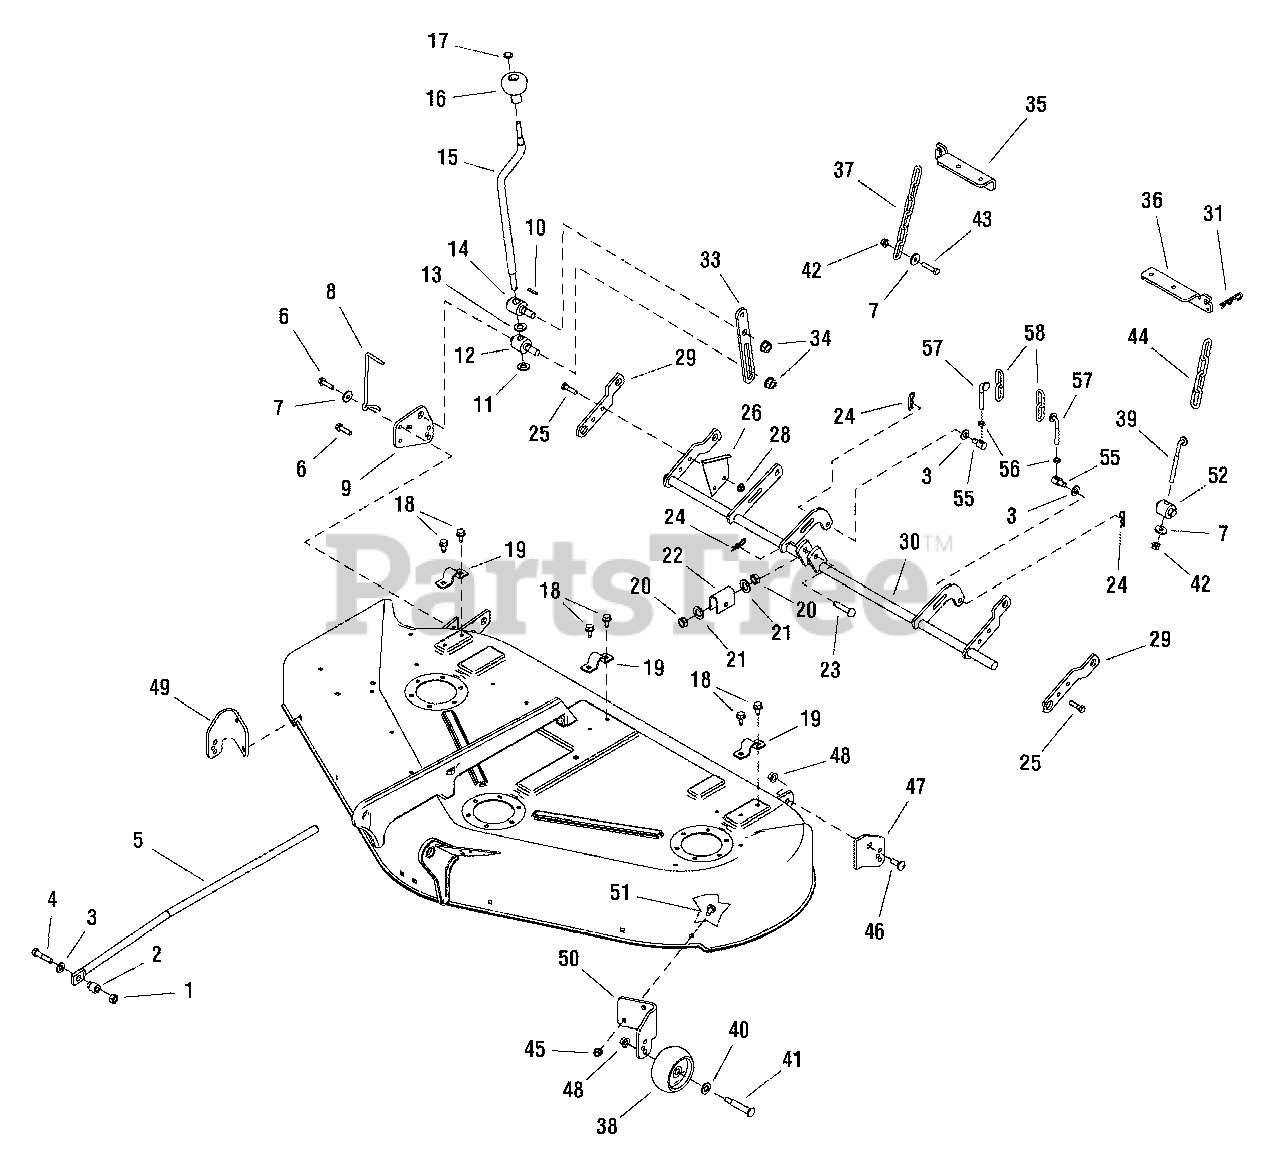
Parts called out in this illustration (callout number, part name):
1	NUT, Hex Flange, 3/8-16
2	SPACER, 3/8 x 3/4 x 15/16
3	WASHER, 3/4
4	CAPSCREW, Hex Head, 3/8-16 x 1-3/4
5	ROD, Adjusting
6	SCREW, Hex Washer Head Taptite 5/16-18 x 1-1/4
7	WASHER, 5/16
8	INDICATOR, Cutting Height
9	SUPPORT, Plate
10	PIN, Spring
11	WASHER, Detent
12	TRUNNION, 1-1/4
13	WASHER, 1/2
14	TRUNNION, 1-1/4
15	CRANK, Height Adjustment
16	KNOB, Spinner
17	NUT, Push Pal 3/8 Stud Capped
18	SCREW, Hex Washer Head Taptite 5/16-18 x 3/4
19	STRAP
20	NUT, Hex 5/8-11
21	WASHER, 5/8
22	TRUNNION
23	PIN, Round Head Drilled 3/8 x 2
24	CLIP, Hair Pin
25	CAPSCREW, Hex Head, 5/16-18 x 1 1/4
26	BRACKET, Height Of Cut 16GA
28	NUT, Hex Flange 5/16-18 Whiz Lock Small
29	ARM, Rear R.H.
30	SHAFT ASSEMBLY, Rocker
31	CLIP, Hair Pin
33	STOP, Height Adjusting
34	NUT, Hex Flange, Two-Way Lock, 1/2-13
35	HANGER, RH
36	HANGER, LH
37	CHAIN, Link
39	ROD, Height Adjusting
40	WASHER, 1/2
41	BOLT, Wheel 3/8-16
42	NUT, Hex Flange 5/16-18
43	CAPSCREW, Hex Head 5/16-18 x 1-1/2 G8
44	CHAIN, Link
45	NUT, Hex Flange 5/16-18 Whiz Lock Large
46	CARRIAGE BOLT, 3/8-16 x 1 G5
47	SUPPORT, Roller L.H.
48	NUT, Hex Flange 3/8-16 ESNA
49	BRACKET, Wheel Gauge R.H.
50	BRACKET, Wheel Gauge L.H.
51	CARRIAGE BOLT, 5/16-18 x 7/8 G5
56	NUT, Hex Jam 5/16-18
57	ROD, Height Adjusting 5/16-18
58	CHAIN, Link
